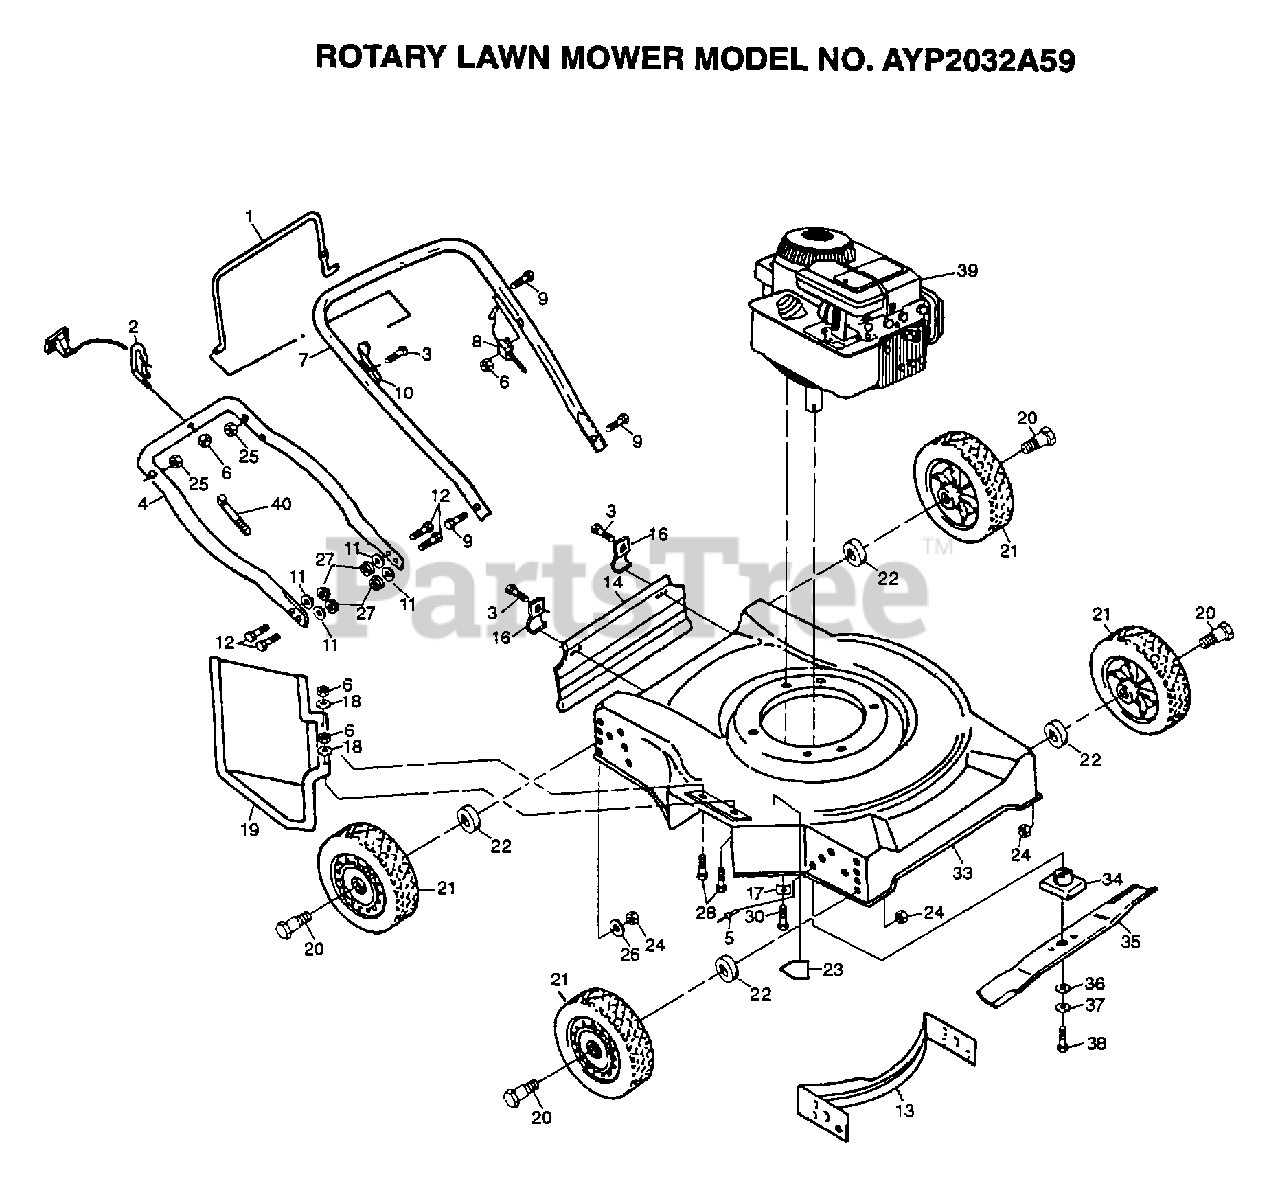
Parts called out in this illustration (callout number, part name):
1	CONTROL BAR PM
2	ROPER GUIDE PM
3	TAPPING SCREW
4	HANDLE LWR PM
5	BLIND RIVET
7	UPPER HANDLE
8	"CABLE,ZONE PM"
9	BOLT 1/4-20-1 1/2
10	"BRKT,UPSTOP PM"
11	STEEL WASHER
14	SKIRT.REAR.20RD.
16	"BRKT,DEFL PM"
19	"GRD,DISCHARGE"
20	AXLE BOLT
21	WHEEL&TIRE
23	DECAL-DANGER PM
24	LOCKNUT PM
27	LOCKNUT
28	BOLT LT
30	SCREW
33	KIT.HSG.20SD.PUSH
34	BLADE ADAPTOR
35	BLADE.STAND.20INC
36	"WASHER,HARDEN"
37	LOCKWASHER
38	SCREW
